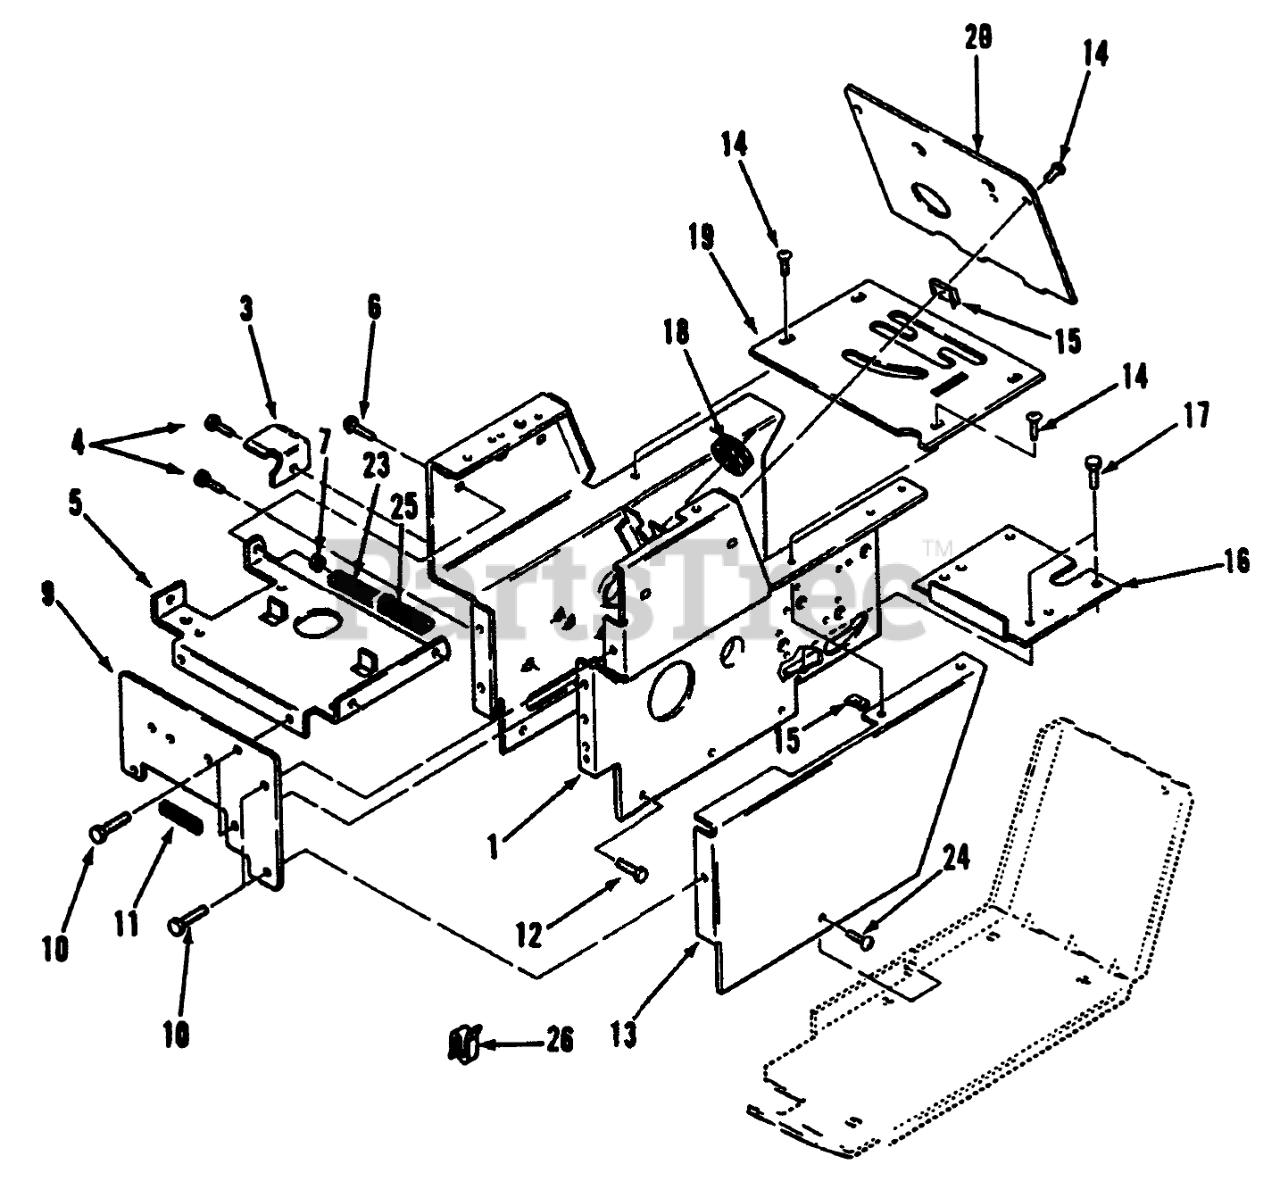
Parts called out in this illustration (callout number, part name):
1	Handstand
3	Belt Bracket
4	SCREW
5	SUPORT-BATERYB
6	BOLT CARR. 5/16X1/2 BK
7	NUT-HEX
9	Front Plate
10	SCREW
11	EDGE TRIM 4IN OF 102896
12	SCREW
13	Cover-Side LH
14	Screw
16	Cover-Dust
17	SCREW
18	GROMMET
19	Plate-Shift Cover
20	Plate-Hood Stand
23	EDGE TRIM 5" OF 102896
24	Screw
25	EDGE TRIM 2" 102896
26	SPEED CLIP
